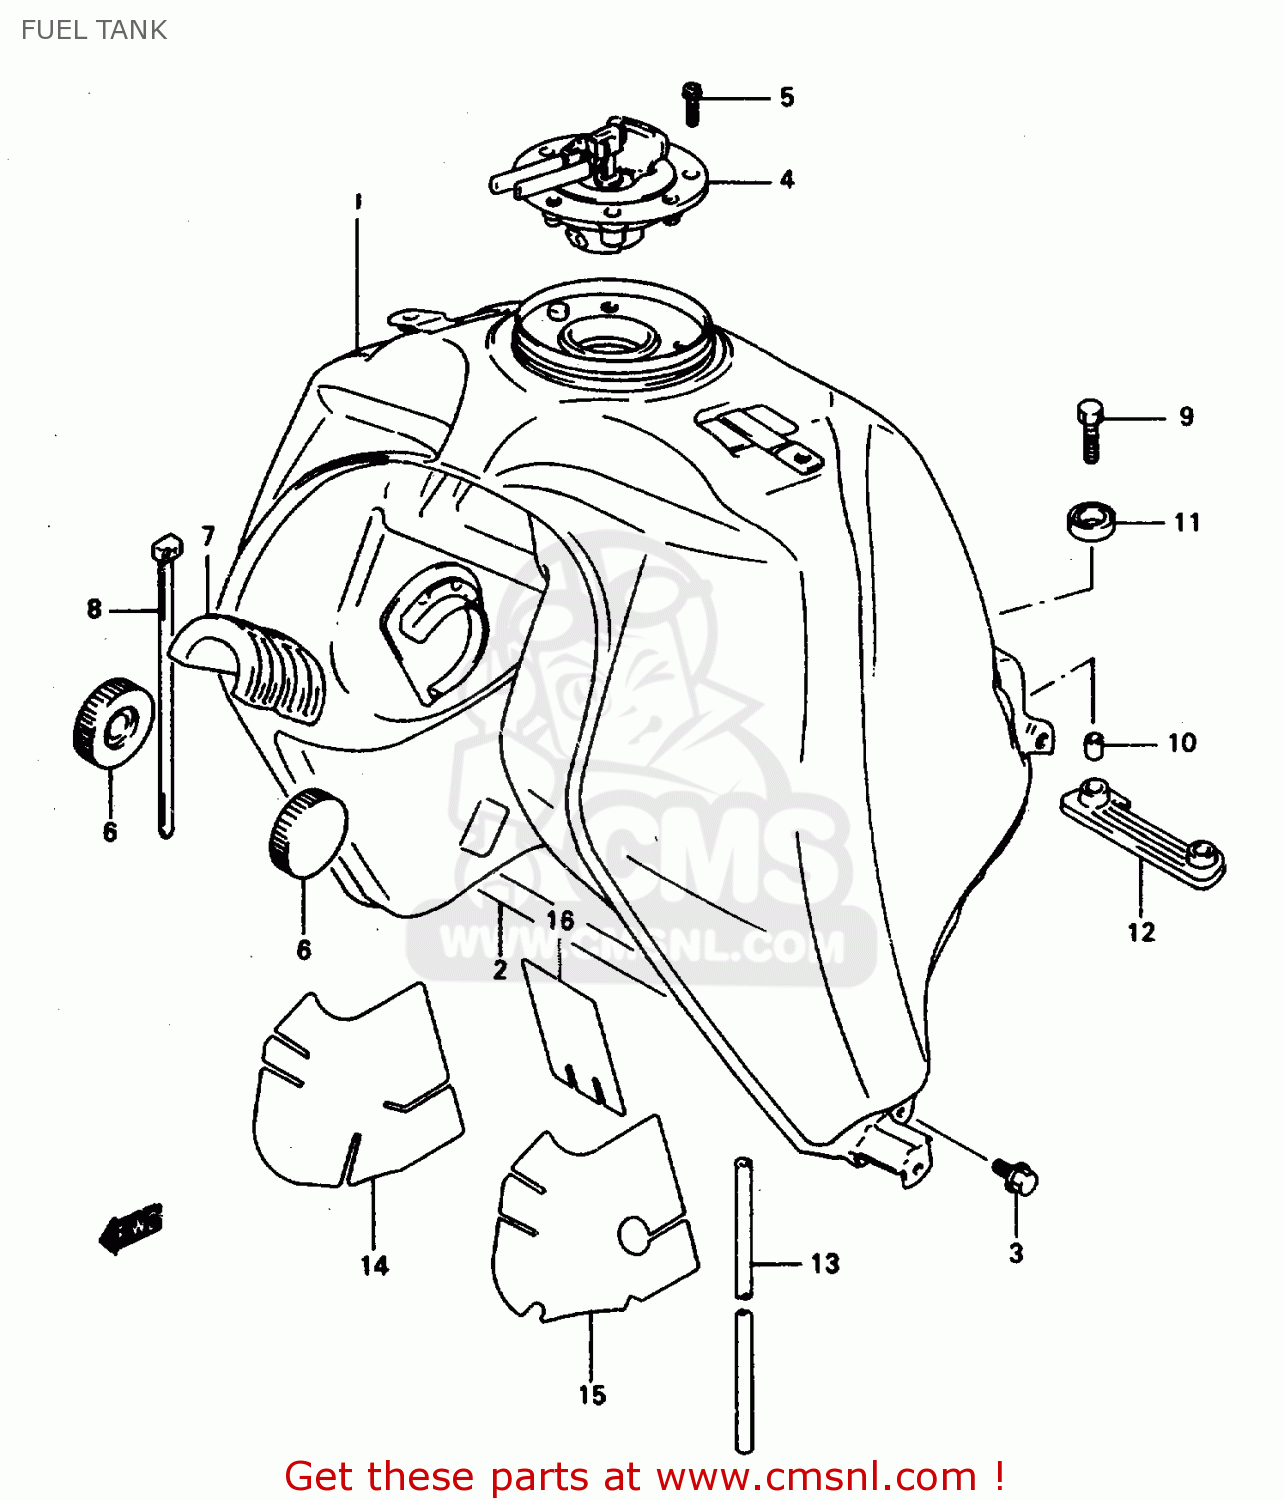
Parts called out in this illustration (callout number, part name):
1	TANK,FUEL BLACK
2	TUBE, FUEL TANK
3	BOLT
4	CAP SET,FUEL TANK
5	BOLT(5X20)
6	CUSHION,FUEL TANK FR
7	CUSHION, UPPER
8	CLAMP(L:250)
9	BOLT, REAR
10	SPACER(8.5X12X18)
11	CUSHION,FUEL TANK RR UPR
12	CUSHION FUEL T
13	HOSE(7X10.2X2000)
14	HEATSHIELD,FUEL TANK,R
15	HEATSHIELD,FUEL TANK,L
16	HEATSHIELD,FUEL TANK CTR
